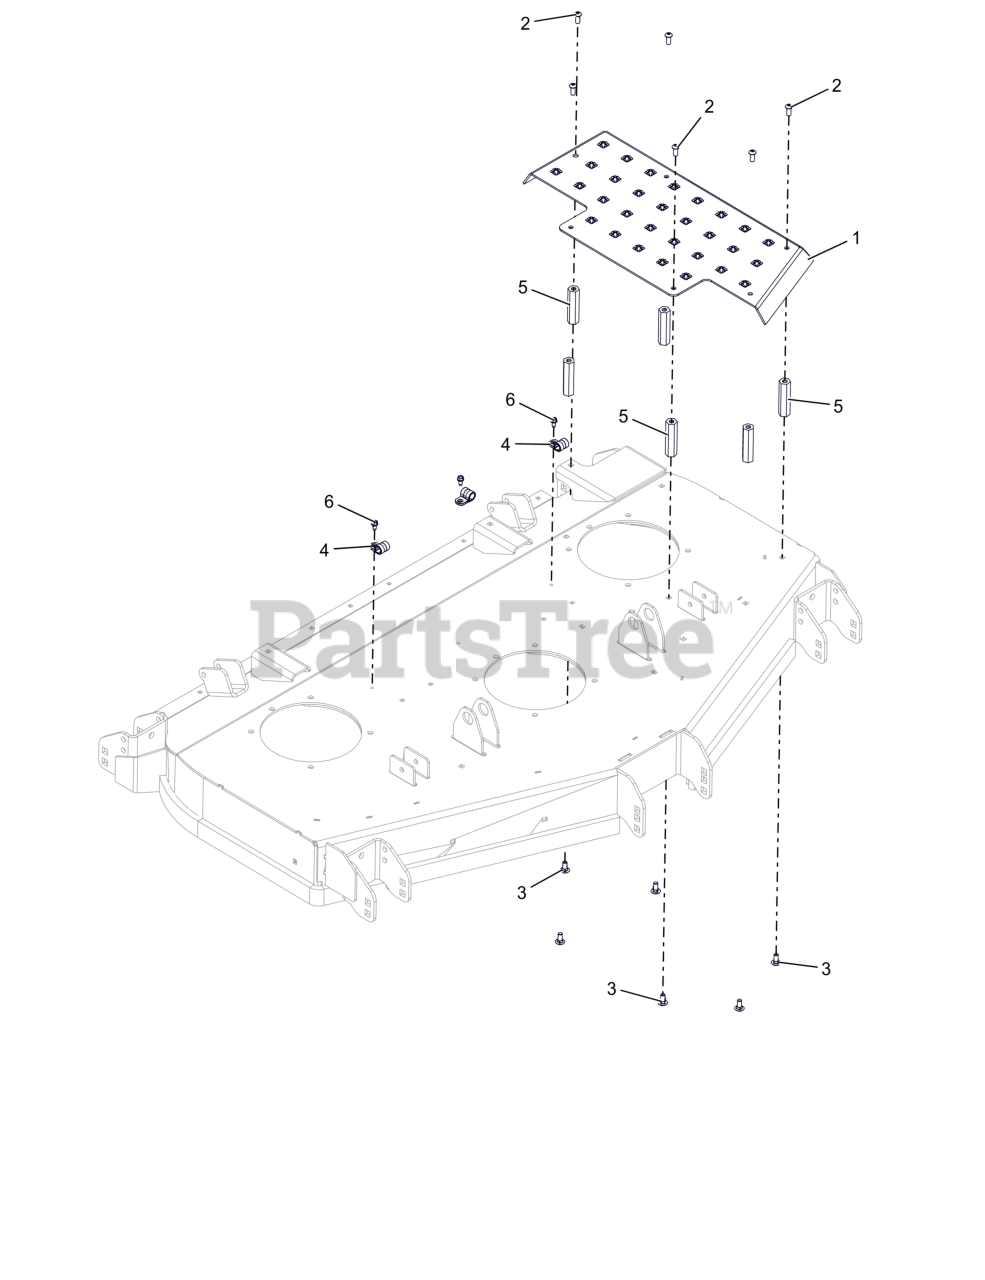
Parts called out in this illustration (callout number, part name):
1	PLATFORM, WLDMT 52 RD DECK STEP (RED)
2	SCR-SKH .31-18X.75 BTNHD YWZC
3	BTL,RHSN .313-18 X 0.75 G5 ZCC LT
4	CLAMP, CUSHIONED STEEL
5	NUT, COUPLING .31-18 X 3.00
6	SCR-TAP .25-20X.50 HWH ZCC
